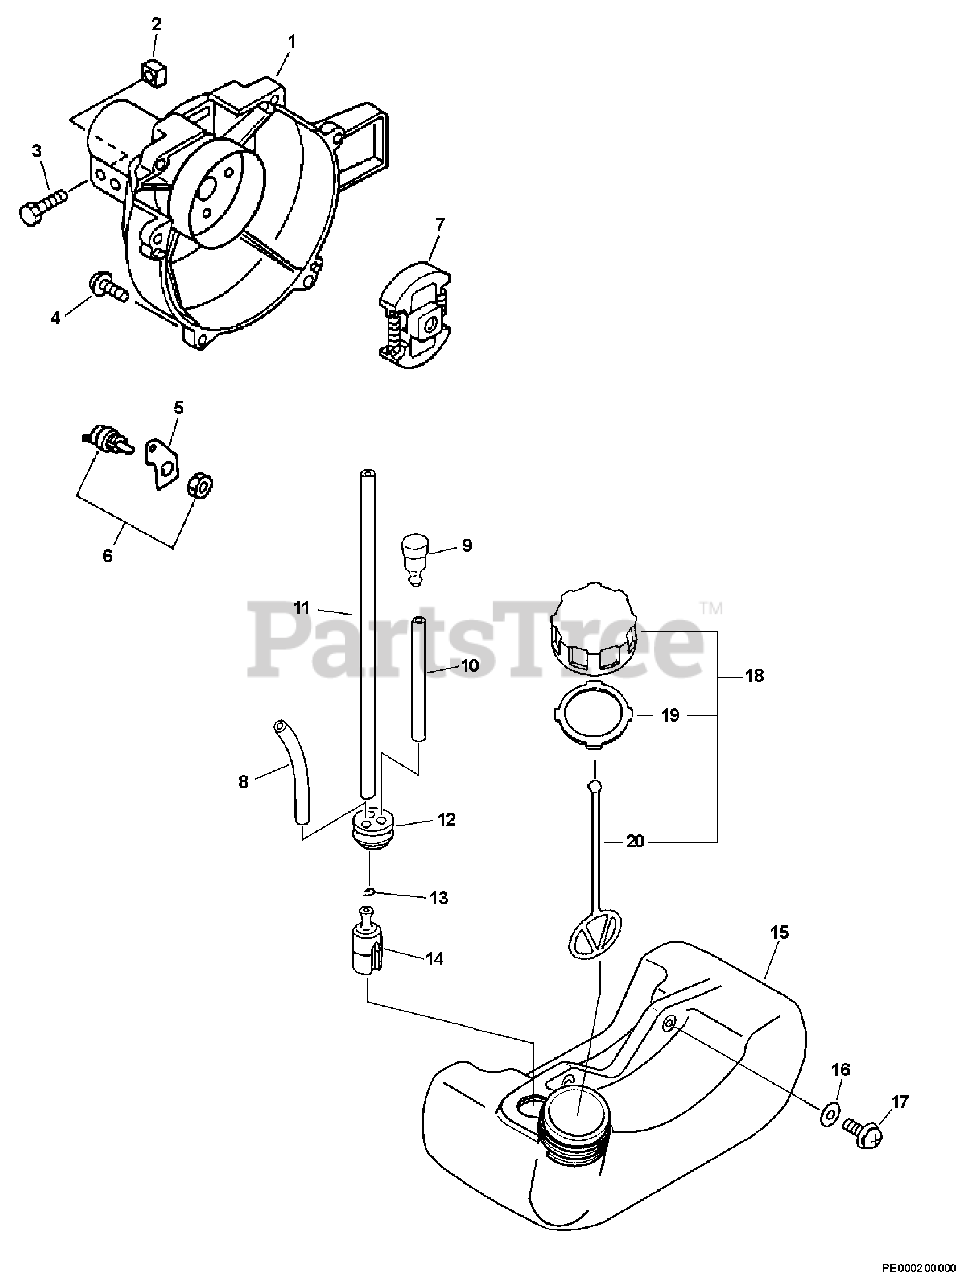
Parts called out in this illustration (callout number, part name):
1	FAN CASE ASSY
2	NUT - 5 -- SQUARE
3	BOLT - 5X28
4	SCREW - 4X18
5	BRACKET, SWITCH
6	IGNITION SWITCH ASSY
7	CLUTCH ASSY
8	PIPE - 3X6X90 -- CLEAR
9	VENT, FUEL TANK
10	PIPE - 3X5X70 -- BLACK
11	PIPE - 3X5X180 -- BLACK
12	GROMMET
13	CLIP - 6
14	FILTER, FUEL
15	TANK, FUEL
16	WASHER - 5
17	SCREW - 5X20
18	CAP ASSY - ORANGE
19	GASKET, CAP
20	CONNECTOR, CAP
